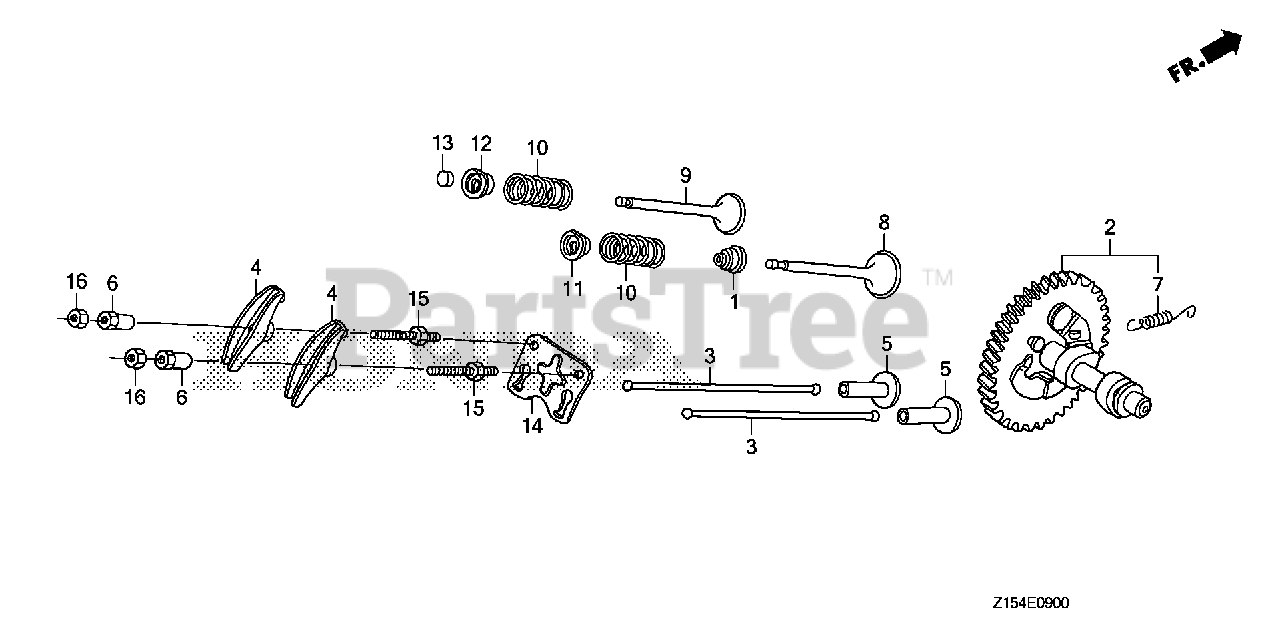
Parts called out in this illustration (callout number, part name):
1	SEAL, VALVE STEM
2	CAMSHAFT ASSY. (JLH)
4	ARM, VALVE ROCKER
5	LIFTER, VALVE
6	PIVOT, ROCKER ARM
7	SPRING, WEIGHT RETURN
8	VALVE, IN.
9	VALVE, EX.
10	SPRING, VALVE
11	RETAINER, IN. VALVE SPRING
11	RETAINER, VALVE SPRING
12	RETAINER, EX. VALVE SPRING
13	ROTATOR, VALVE
14	PLATE, PUSH ROD GUIDE
15	BOLT, PIVOT (8MM)
16	NUT, PIVOT ADJUSTING
